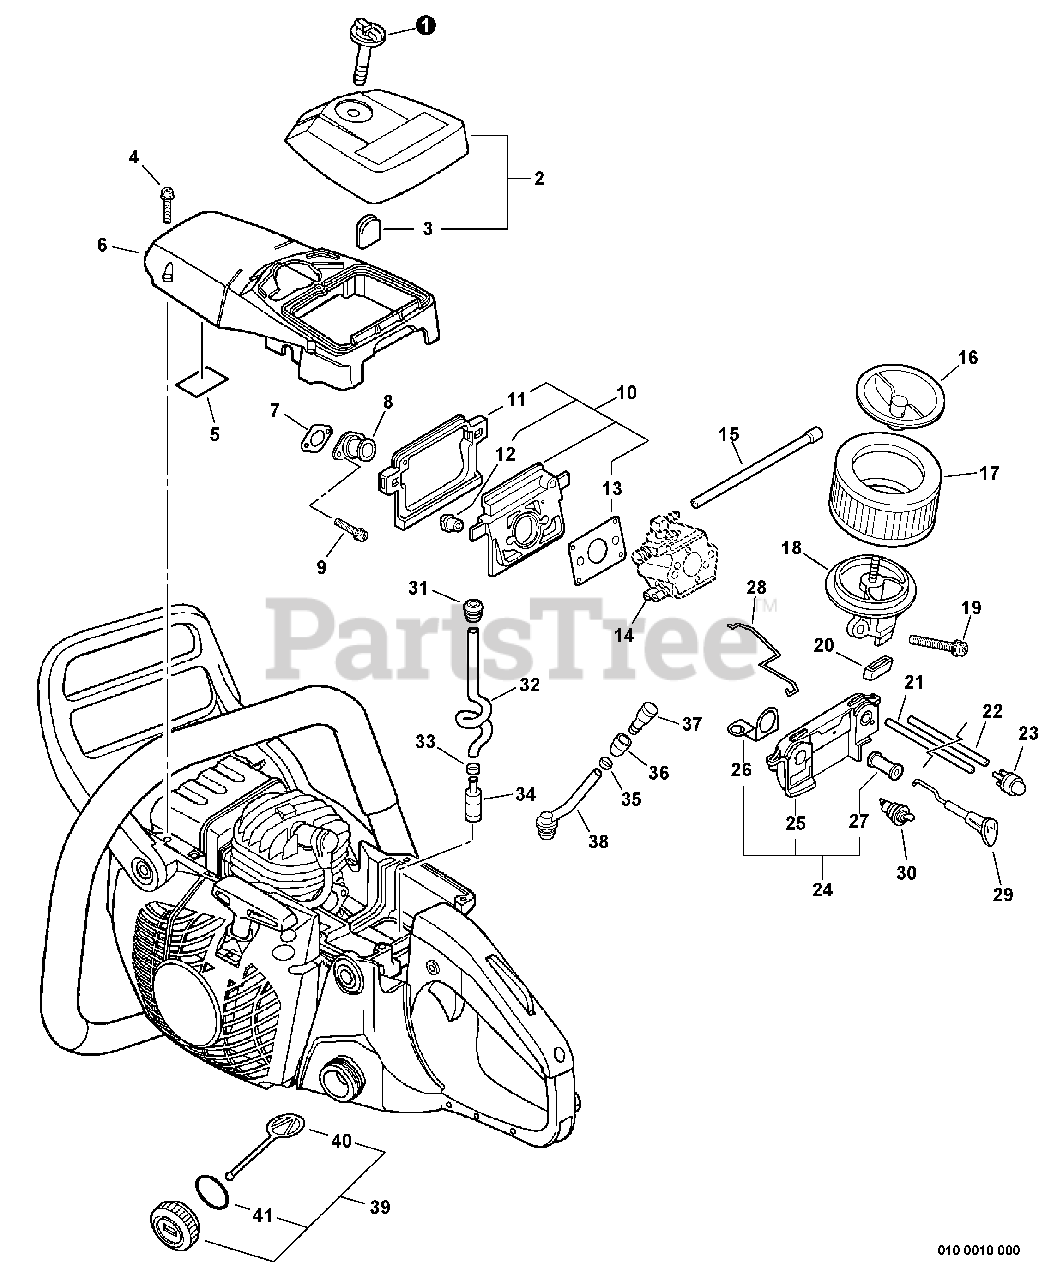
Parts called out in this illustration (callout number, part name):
1	THUMBSCREW
2	COVER ASSY, AIR FILTER
4	SCREW 5×25
5	SHIELD, HEAT
6	COVER, ENGINE
7	GASKET, INTAKE
8	ADAPTOR, INTAKE
9	SCREW 5×12
10	INSULATOR KIT, INTAKE
11	CUSHION
13	GASKET, INTAKE
14	CARBURETOR
15	PIPE, IMPULSE 3×5×110
16	CAP, AIR FILTER
17	FILTER, AIR
18	MOUNT, AIR FILTER
19	BOLT 5×50
21	PIPE, PURGE 2.5×5×140
22	PIPE, PURGE 2.5×5×140
23	BULB, PURGE
24	BRACKET KIT, SWITCH
25	BRACKET, SWITCH
26	TERMINAL, SWITCH
27	GROMMET, CHOKE
28	ROD, THROTTLE
29	ROD, CHOKE
30	SWITCH, ON-OFF
31	GROMMET, FUEL
32	PIPE, FUEL 3×6×165
33	CLIP Ø6.5 MM
34	FILTER, FUEL
35	CLIP Ø6.5 MM
36	HOLDER, VENT
37	VENT ASSY
38	GROMMET, W/VENT PIPE 3×6×105
39	CAP ASSY, FUEL
40	CONNECTOR, CAP L= 60 MM
41	O-RING 22
